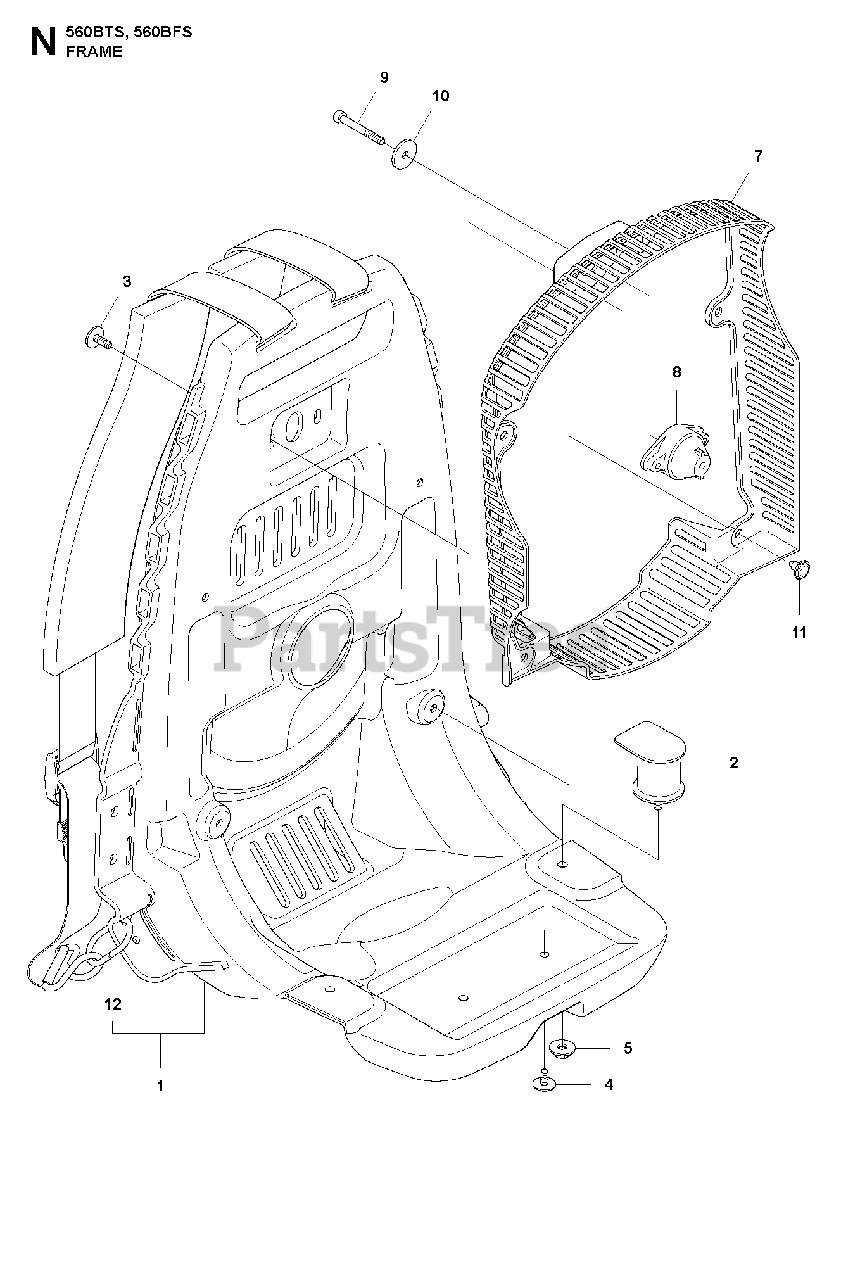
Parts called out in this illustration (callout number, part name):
1	FRAME ASSY
7	NET
8	DAMPER UPPER
12	RING
